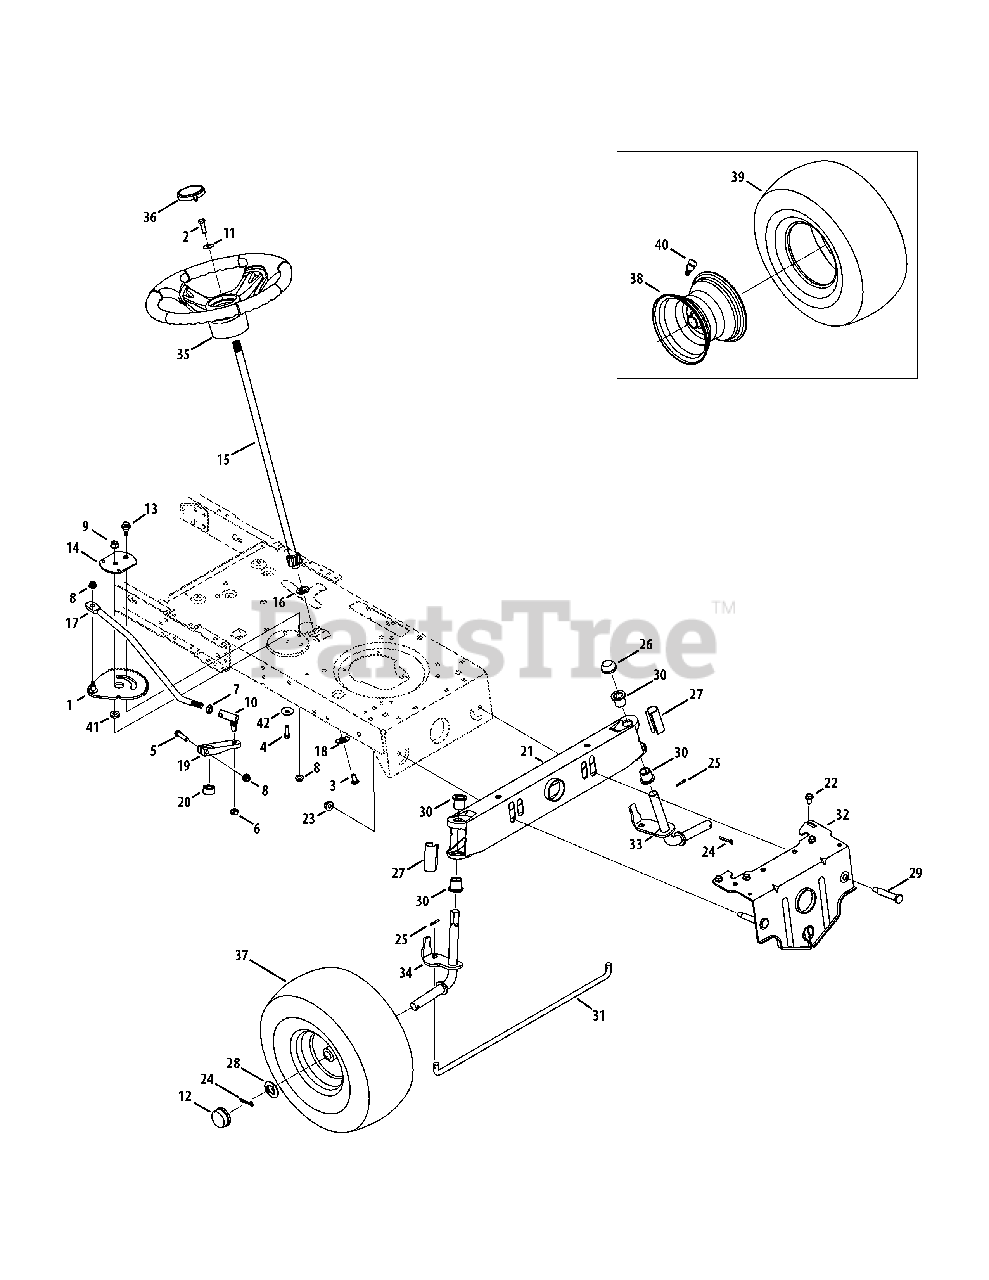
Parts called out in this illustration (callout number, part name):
1	Gear Assembly, Steering
2	Screw, 5/16-18, 1.00, Gr5, Lock
3	Screw, Mach, 5/16-18, 0.750
4	Hex Head Screw, 3/8-16 x 1.00
5	Screw, 5/16-18, 1.75, Gr5
6	Nut, Jam Lock, 3/8-24
7	Nut, Jam, 7/16-20, Gr2
8	Nut, Flange Lock, 5/16-18, Grf
9	Flangelock Nut, 3/8-16
10	Ball Joint, 7/16-20, Lock
11	Washer, Bell, .340 x .872 x .060
12	Hub Cap
13	Shoulder Screw, 5/16-18
14	Stabilizer Plate
15	Steering Shaft, 5/8
16	Bearing, Flange, Hex 5/8
17	Drag Link, Steering
18	Cap, 1.25 x .16
19	Steering, Block
20	Spacer, .710 ID x .125 OD x .56
21	Pivot Bar Axle Assembly
22	Screw, 5/16-18, 0.750
23	Nut, Flange Lock, 3/8-16, GrF
24	Pin, Cotter, 5/32, 1.25
25	Pin, Cotter, 1/8 x 0.75
26	Push Cap, 3/4
27	Axle Cap
28	Washer, Flat, .781 x 1.59
29	Screw, Shlder, .500 x 2.380, 3/8-16
30	Flange Bearing
31	Tie Rod
32	Pivot Bar Bracket
33	Axle Assembly LH
34	Axle Assembly RH
35	Steering Wheel, Standard Grip
36	Cap, Steering Wheel (Crafts. logo)
37	Wheel Assembly
39	Tire, 15 x 6 x 6 Rd. Shoulder
40	Valve Stem
41	Spacer, .38 ID x .854 OD x .20
42	Bell Washer, .390 x 1.13 x .062
